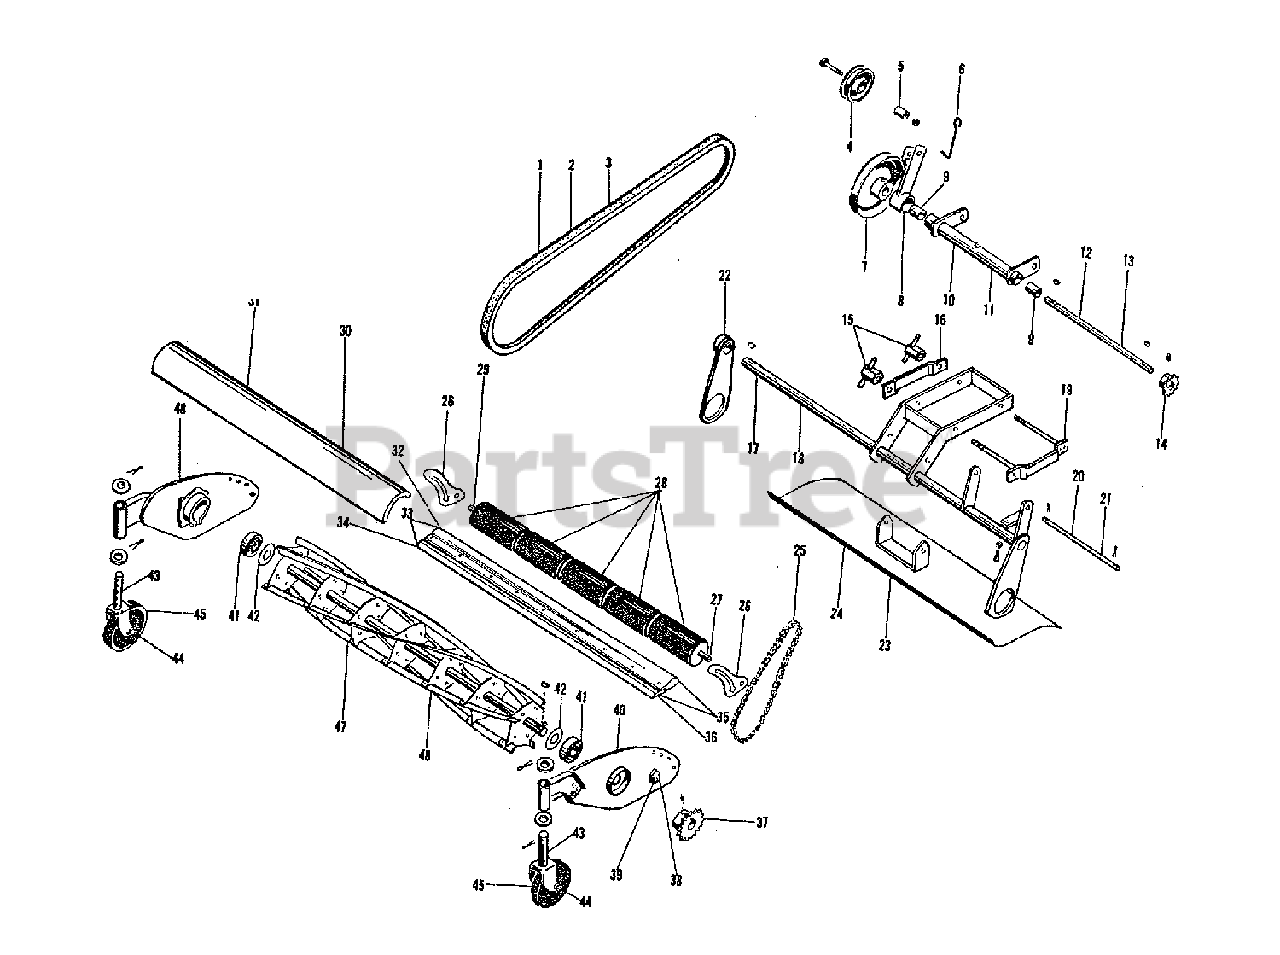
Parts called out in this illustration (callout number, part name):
1	BELT, 34" for 2 HP Only
2	V-BELT, 40"
3	BELT, 39" for 5 HP Only
4	PULLEY, Idler
5	BUSHING, Idler Pulley
6	STOP, Belt
7	PULLEY, Drive
8	LEVER ASSEMBLY, Idler
9	BEARING, Pulley Shaft
10	HOUSING ASSEMBLY, Bearing, 24" Only
11	HOUSING ASSEMBLY, Bearing, 30" Only
12	SHAFT, Pulley, 24" Only
13	SHAFT, Pulley, 30" Only
15	NUT, Wing, Complete
16	HITCH, Side Plate
17	ARM ASSEMBLY, Push, 30" Only
18	ARM ASSEMBLY, Push, 24" Only
19	CLAMP ASSEMBLY, Hitch
20	SHAFT, Bearing, Housing Arm, 30" Only
21	SHAFT, Bearing, Housing Arm, 24" Only
22	BAR ASSEMBLY, Push, R.H.
23	FENDER ASSEMBLY, Grass, 30" Only
24	FENDER ASSEMBLY, Grass, 24" Only
25	REEL CHAIN, 25" Long
26	BRACKET, Roller
27	SHAFT, Roller, 24" Only
28	ROLLER, 24" Only
28	ROLLER, 30" Only
29	SHAFT, Roller, 30" Only
30	BRUSH BAR, 30" Only
31	BRUSH BAR, 24" Only
32	BAR, Cutter, 30" Only
33	BAR ASSEMBLY, Cutter, 30" Only
34	BAR, Cutter Blade, w/Rivets, 30" Only
35	BAR, Cutter, Complete, w/Blade, 24" Only
36	BAR, Cutter, Blade, w/Rivets, 24" Only
37	SPROCKET
38	ADJUSTING CAM
39	CAPSCREW, Hex, Head, 3/8"-24 x 7/8"
40	FRAME ASSEMBLY, L.H. Side
41	BEARING, Ball
42	BEARING, Reel Washer
43	YOKE ASSEMBLY, Caster
44	AXLE, Caster
45	WHEEL, Caster, w/Bearings
46	REEL ASSEMBLY, L.H., w/Bearing, 30" Only
47	REEL ASSEMBLY, L.H., w/Bearing, 24" Only
48	FRAME ASSEMBLY, R.H. Side
